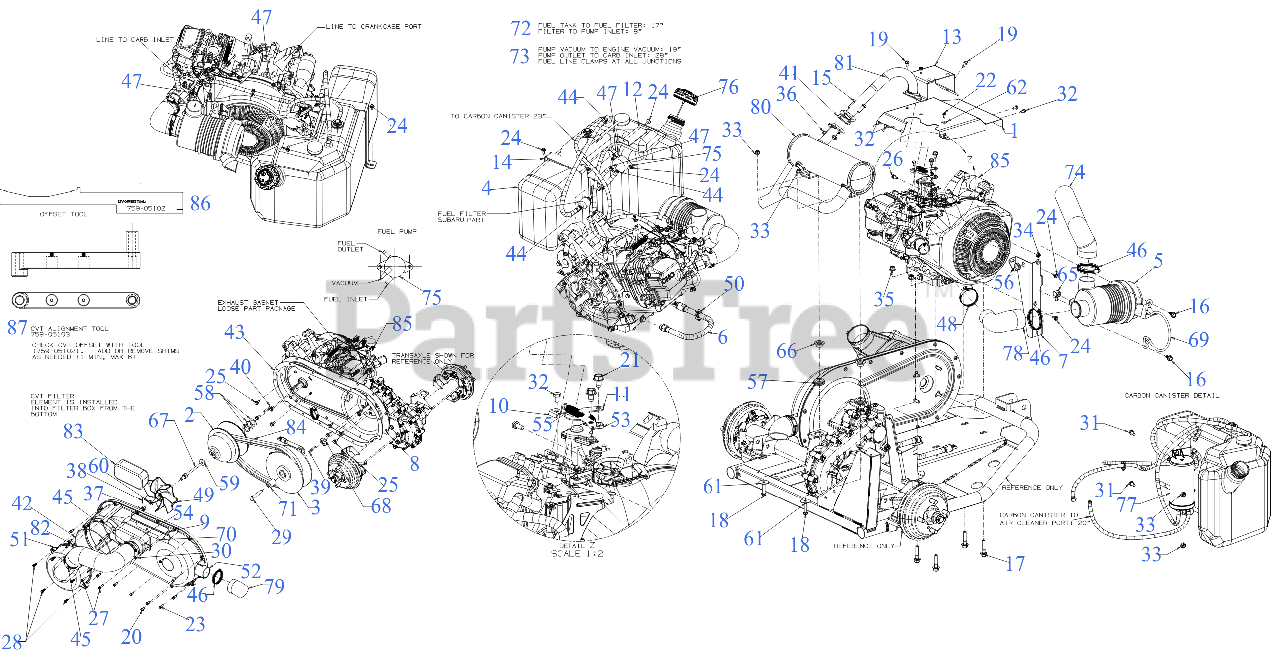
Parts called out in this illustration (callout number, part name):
1	ENGINE COVER ASSEMBLY
2	CVT DRIVER CLUTCH ASSEMBLY
3	CVT DRIVEN CLUTCH ASSEMBLY
4	FUEL TANK ASSEMBLY (5 GALLON)
5	AIR CLEANER FILTER ASSEMBLY
6	OIL DRAIN HOSE ASSEMBLY (M14-1.5MM)
8	BACK COVER PLATE
9	CVT INTAKE TUBE SUPPORT
10	SPRING RETENSION BRACKET
11	THROTTLE MOUNTING BRACKET
12	FUEL TANK TOP BRACKET
13	AIR INLET COVER
14	BRKT:STRAP: FUEL TANK
15	SCREW 5/16-18 x 1.0 GR5
16	SCREW 5/16-18 x .750
17	SCREW 3/8-18 x 1.75 GR5
18	SCREW 5/16-18 x 1.25 GR5
19	SCREW 1/4-20 X.500
20	SCREW 5/16-18 x .625
21	SCREW 5/16-18 x .500
22	SCREW M5-.8X10MM SLOT/TORX
23	SCREW-TT 1/4-20 x .875
24	SCREW M6-1 x .625
25	HEX FLANGE BOLT 5/16-24:0.75
26	SCREW 1/4-20 x .620 GR5
27	SCREW 1/4-20 x 1.00
28	SCREW 1/4-15 x .750
29	SCREW 1/2-20 x 2.75 GR8
30	SCREW 1/4-20 x 2.375
31	SCREW 5/16-18 x .75 GR5
32	SCREW M6-1.0X10MM GR8.8
33	FLANGE LOCK NUT 5/16-18
34	FLANGE LOCK NUT
36	FLANGE NUT
37	HEX NUT CASTLE
38	COTTER PIN-3/32 DIA x 1.00
39	SQUARE KEY 3/16 x 3/16 x 2
40	KEY 1/4 x 3/16
41	EXHAUST GASKET
42	O-RING 7.98 x 8.137 x 0.103
43	CVT COVER SEAL
44	HOSE CLAMP 1/20
45	HOSE CLAMP
46	HOSE CLAMP 2-3"
47	HOSE CLAMP 0.470
48	ADJUSTABLE HOSE CLAMP 1.31-2.25"
50	DRAIN HOSE CLIP
51	CVT FAN COVER
52	CVT COVER
53	CONTROL PANEL COVER
54	CVT FILTER HOUSING
55	EXTENSION SPRING
57	GROMMET .75 x 1.063 x .4375
58	FLAT WASHER
59	FLAT WASHER
60	FLAT WASHER .510X.995
61	FLAT WASHER .322 ID x 1.25 x .060
65	90 DEGREE FITTING
66	SHOULDER SPACER .750 x .145
67	THREADED FAN ROD
68	SHOULDER SPACER
69	AIR FILTER STRAP ROD
71	CVT DRIVEN SPACER
72	FUEL HOSE LOW PERMEATION 28"
73	FUEL HOSE LO PERMEATION 62"
74	AIR INLET HOSE
75	ENGINE FUEL PUMP
76	FUEL CAP W/TETHER VENTED
77	CARBON CANISTER
78	AIR FILTER INTAKE HOSE
79	CVT EXHAUST HOSE
81	EXHAUST PIPE
82	CVT INTAKE TUBE
83	CVT INLET FILTER
84	CVT BELT 4X2
85	COMPLETE ENGINE LTV
86	TOOL - CVT OFFSET
87	TOOL - CVT ALIGNMENT
